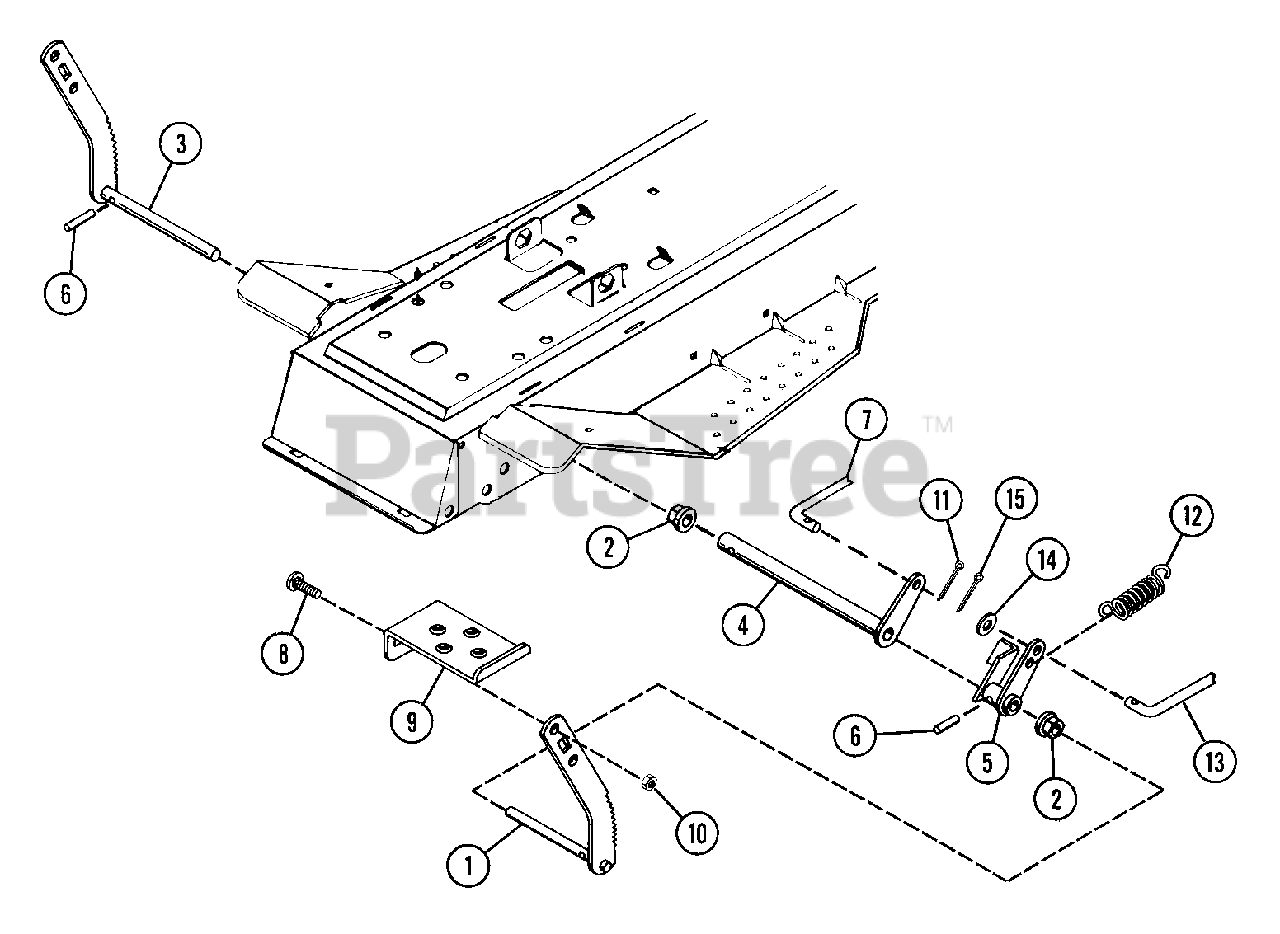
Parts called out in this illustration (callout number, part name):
1	CLUTCH ARM
2	FLANGE BUSHING
3	BRAKE PEDAL ARM
4	BRAKE ARM
5	CLUTCH PEDAL ARM
6	PIN-ROLL .188X1.00
7	BRAKE ROD
8	BLT-RDHDSQNK .38-16X.75 SHT PL
10	NUT-LK-JAM-CTR .375-16 PL
11	PIN-COTR .09X1.87 PL
12	SG-TENS .035X.45X2.75 WLD 3.5
13	ROD, CLUTCH
14	WSHR-FL-STL .323X.625X.062 PL
15	PIN-COTR .12 X 1.25 PL
